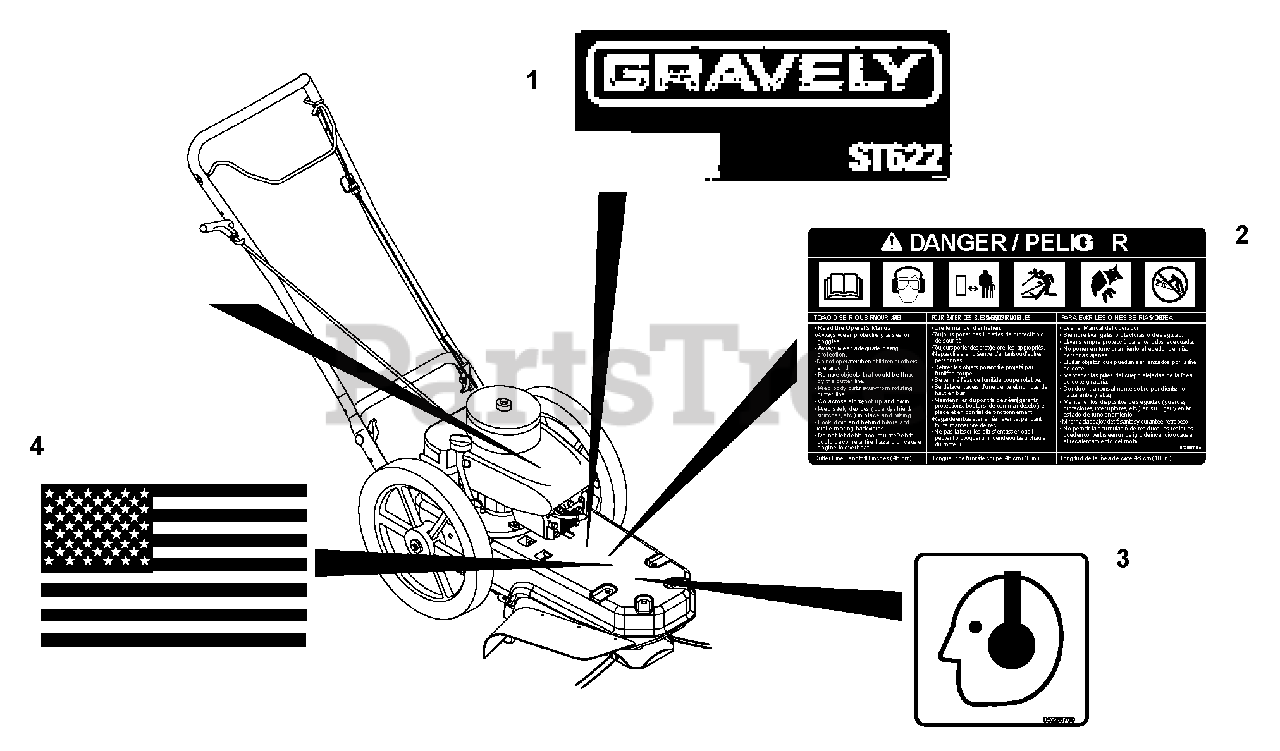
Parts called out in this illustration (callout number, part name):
1	Decal-Gravely ST 622
2	Decal-Danger
3	Decal- Ear Protection
4	Decal - Flag
